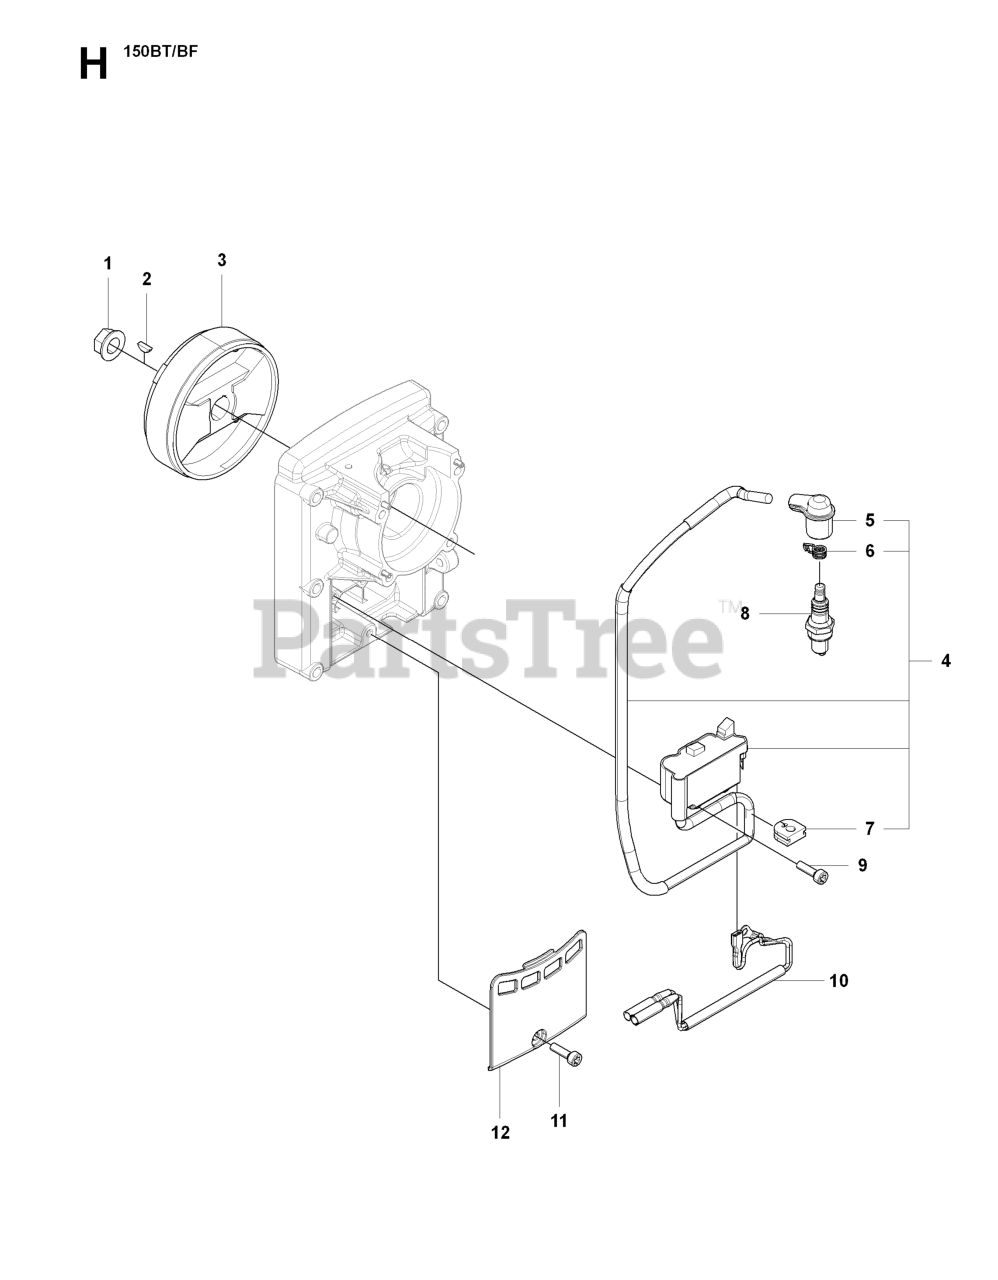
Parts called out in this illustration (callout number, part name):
1	NUT
2	KEY
3	FLYWHEEL
4	IGNITION COIL
5	CAP
6	SPRING
8	SPARKPLUG NGK CMR7H
9	BOLT
10	CORD-C
11	BOLT
